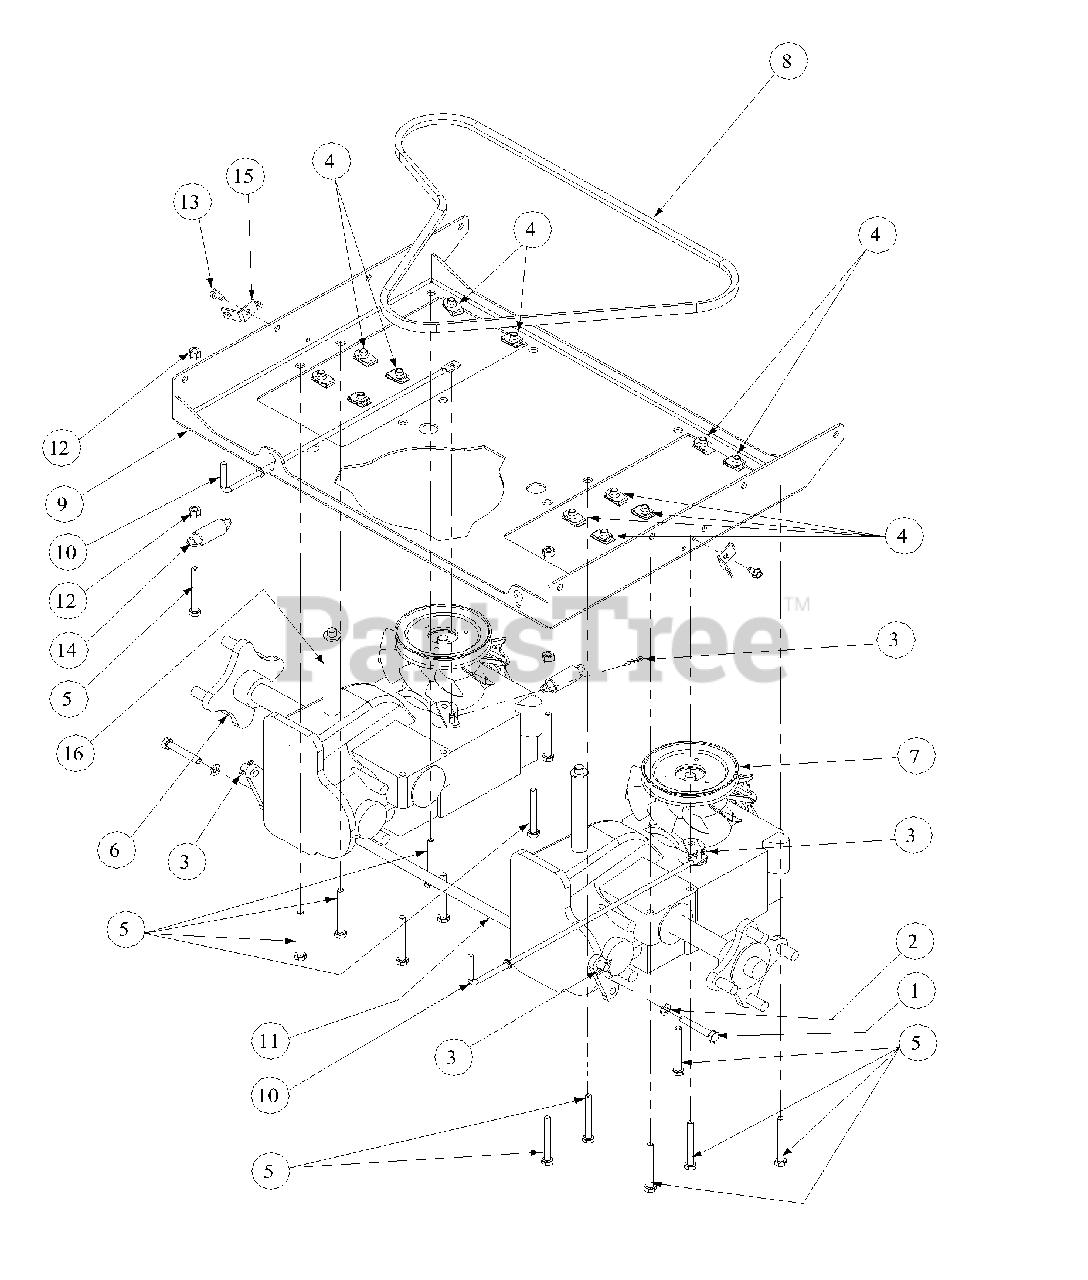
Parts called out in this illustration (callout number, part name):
1	Hex Cap Screw, 5/16-18 x 2.0
2	Flat Washer, .320 ID x .591 OD
3	Cotter Pin, .072 x 1.12 Lg
4	U-Nut, 5/16-18
5	Hex Cap Screw, 5/16-18 x 2.5
6	IZT Transmission, Left Hand
7	IZT Transmission, Right Hand
8	V-Belt, 56.00
9	Transmission Mounting Bracket
11	Transmission Brace Tube
12	Nut, 5/16-18
13	Screw, 1/4-20 x 1/2
14	Extension Spring, .438 OD x 2.50
15	Brake Cable Mounting Bracket
16	Hose, 1/2 Dia. x 4" Long
